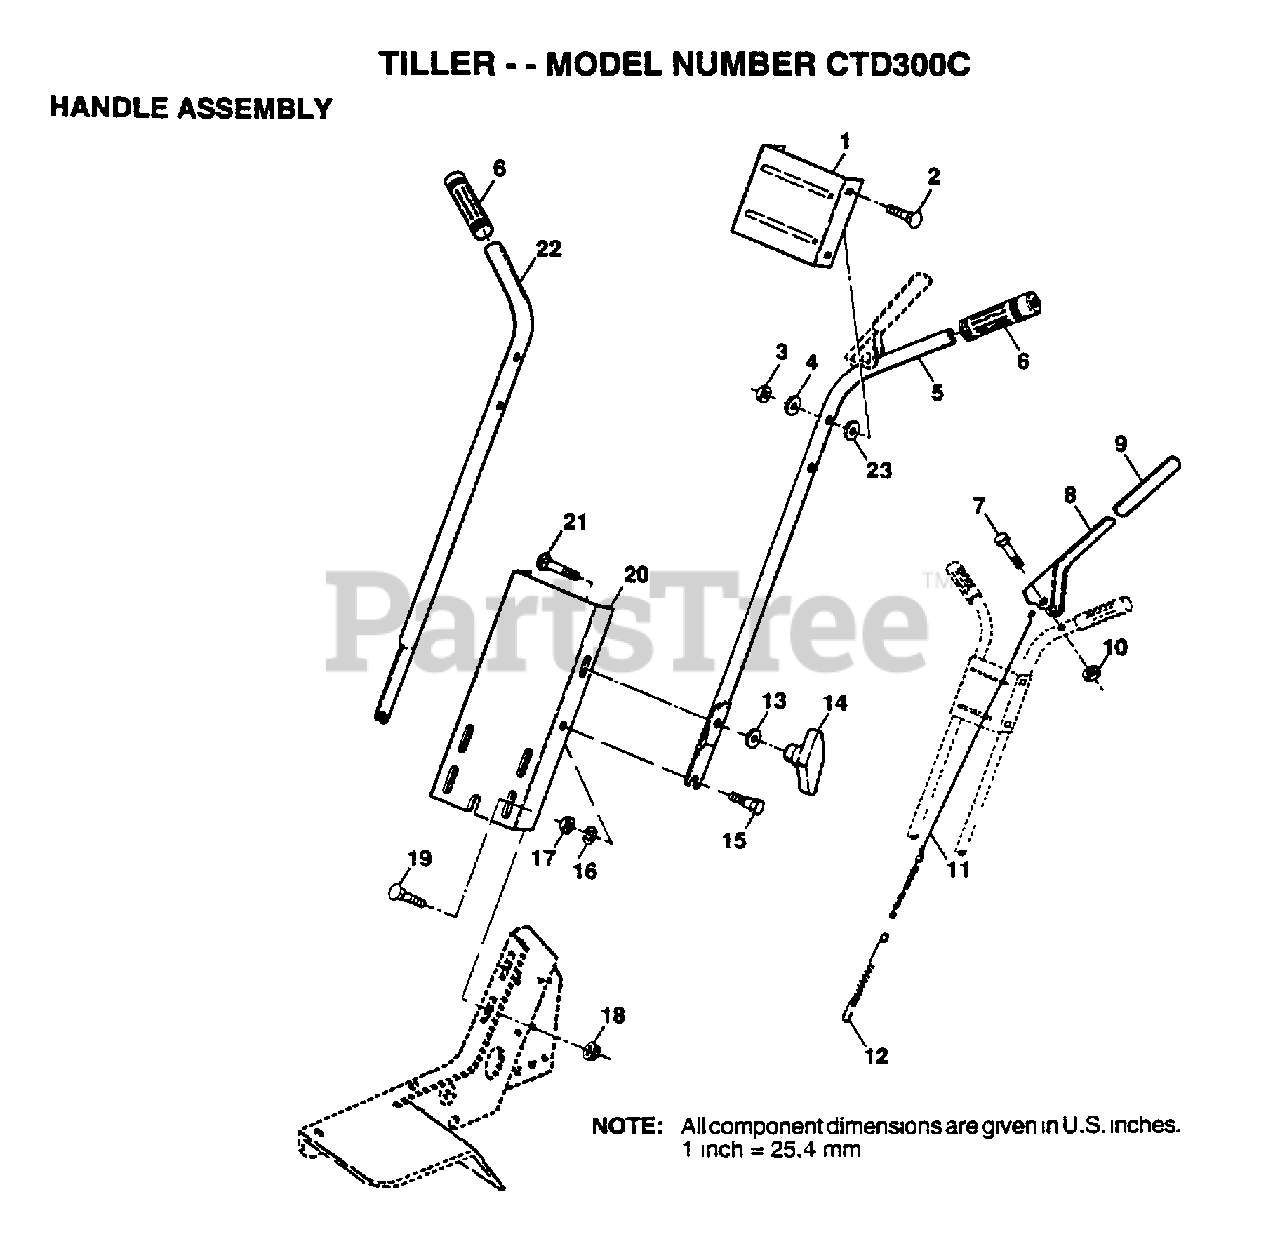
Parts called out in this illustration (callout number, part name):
1	PANEL.CNTRL.HDLE.
2	BOLT
4	WASHER
6	GRIP NUB DOUBLE
7	BOLT.HEX.5/16-1.5
9	GRIP T
12	SPRING EXT TI
13	WASHER
14	KNOB HANDLE
16	LOCKWASHER
17	NUT.HEX.5/16-18
18	NUT
19	BOLT
20	PANEL.HANDLE.TILL
21	BOLT CRT
23	WASHER
